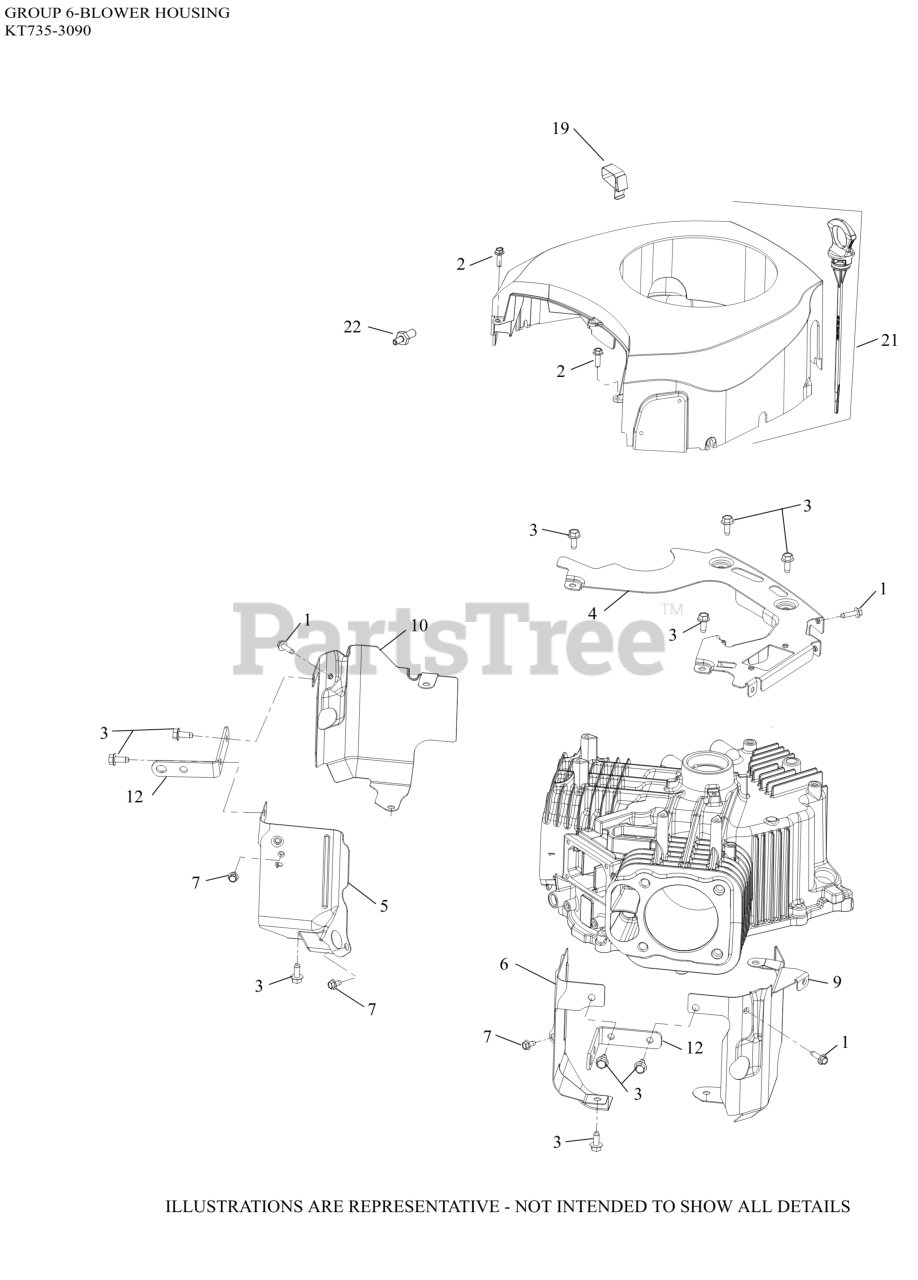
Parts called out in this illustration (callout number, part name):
1	SCREW, THD FRM-USE 25 086 473-S
2	SCREW, HI-LOW
3	SCREW, THREAD FORMING
4	PLATE, BACKING
5	BAFFLE, VALLEY #1
6	BAFFLE, VALLEY #2-USE 32 063 35-S
7	SCREW, THREAD FORMING
9	BAFFLE, LEFT BARREL
10	BAFFLE, RIGHT BARREL
12	STRAP, LIFTING
19	CLIP, BLOWER HOUSING
21	KIT, BLOWER HOUSING
22	BOLT, ENGINE GROUND
